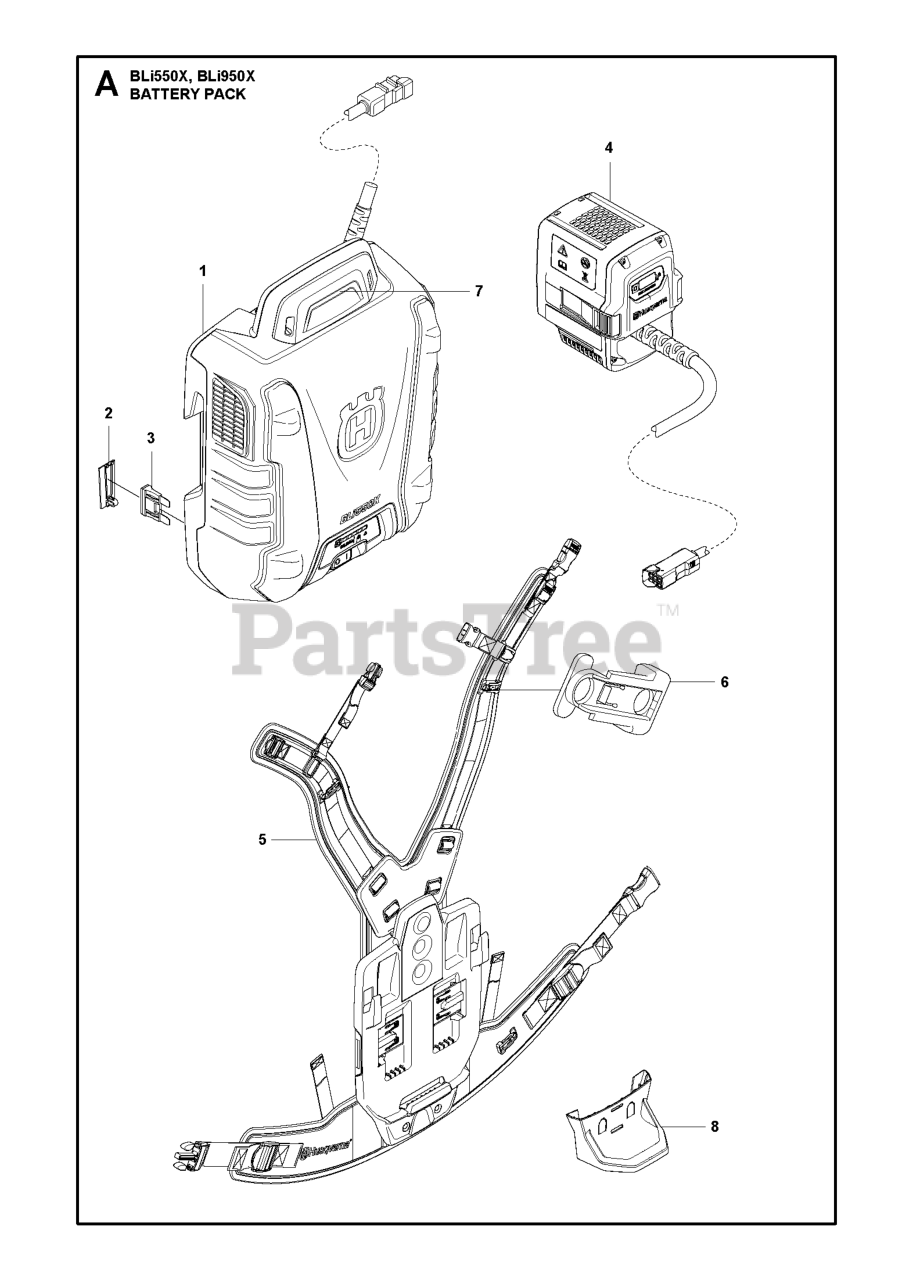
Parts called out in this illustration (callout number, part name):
2	FUSE CAP 60A
4	ADAPTER ASSY
6	FIXING PLATE ASSY
7	HANDLE HANDLE COVER
